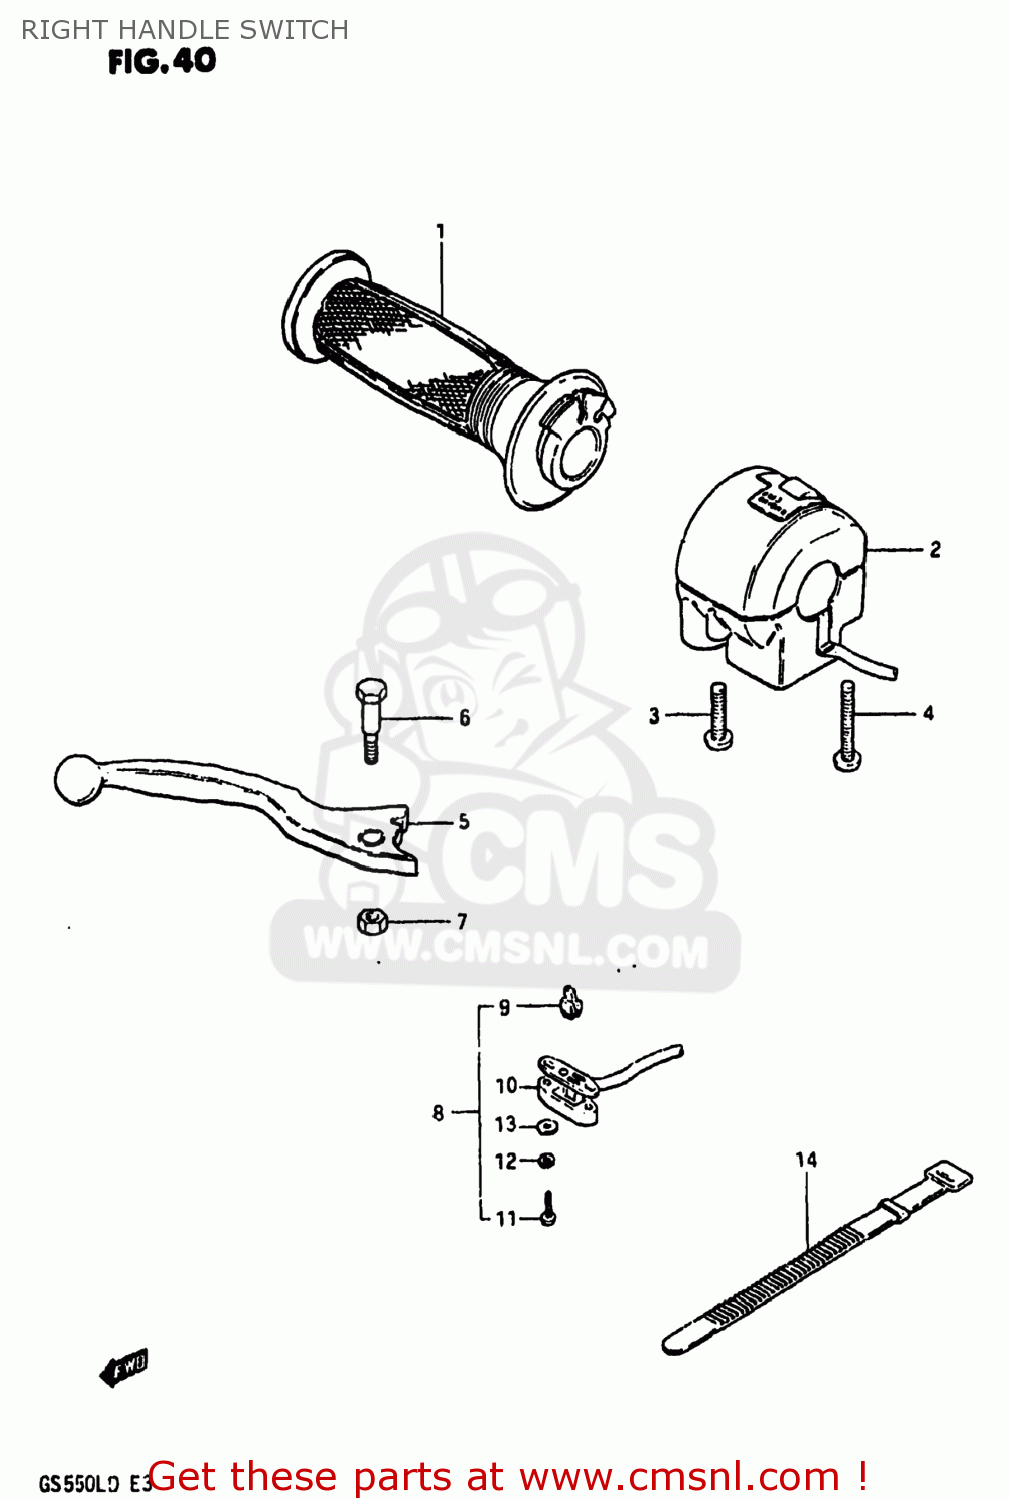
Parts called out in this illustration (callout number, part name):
1	GRIP,THROTTLE
2	SWITCH ASSEMBLY,HANDLE,RIGHT
3	SCREW
4	SCREW
5	LEVER,BRAKE
6	BOLT,LEVER PIVOT
7	NUT 6MM
8	SWITCH ASSEMBLY
9	CONTACT,SWITCH
10	COVER,FR BK TERMINAL BASE
11	SCREW
12	LOCK WASHER
13	WASHER
14	CLAMP(L:120)
